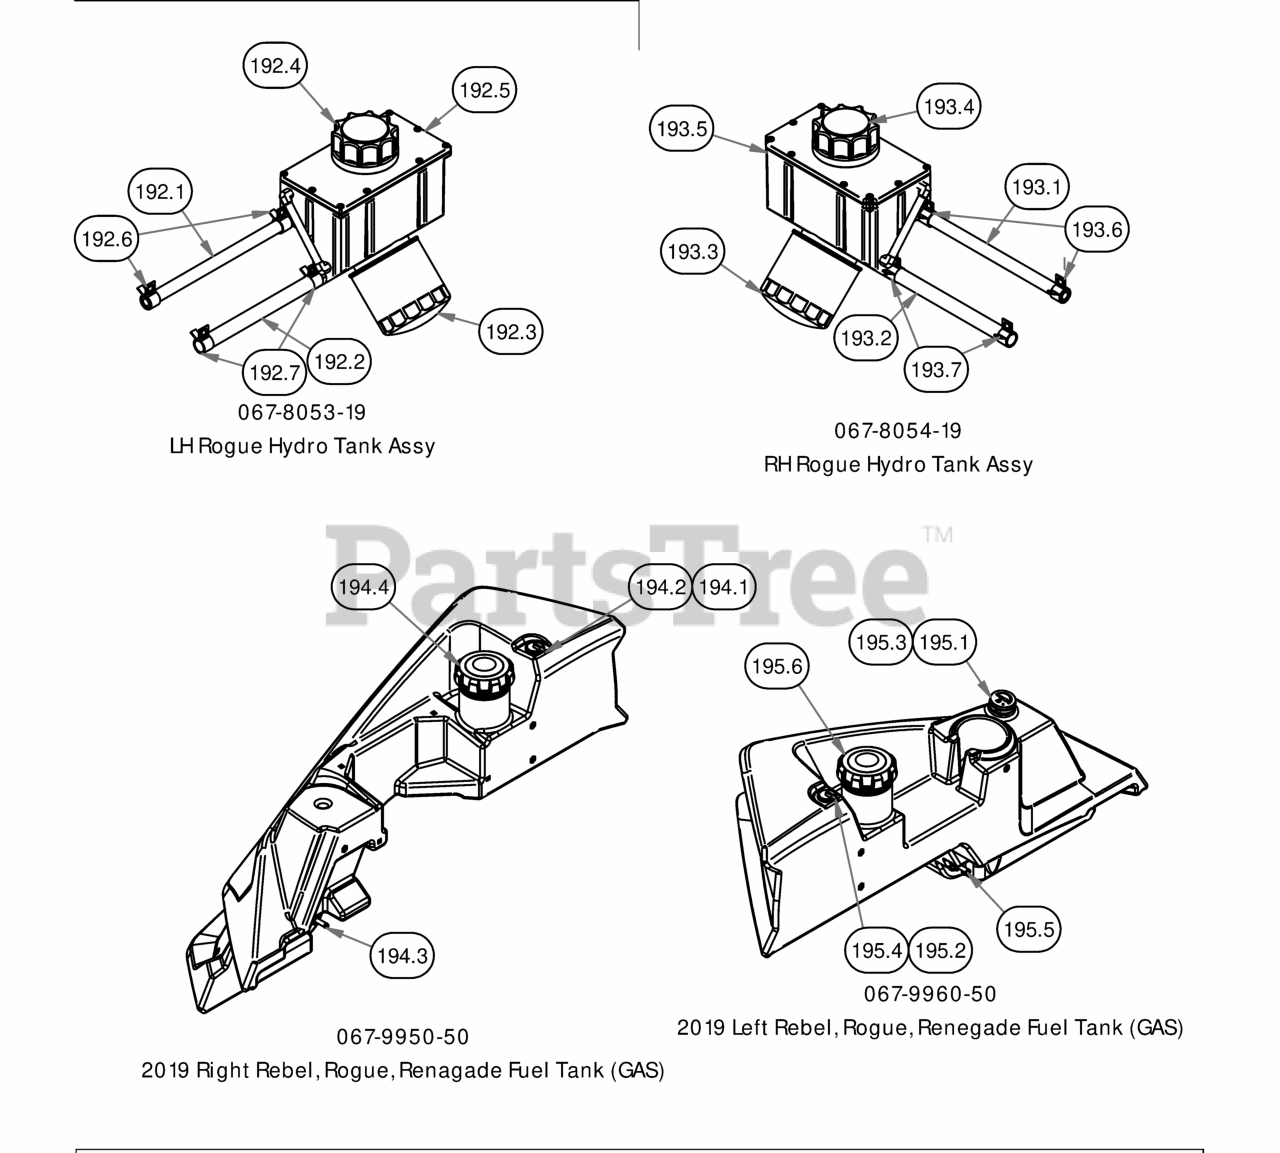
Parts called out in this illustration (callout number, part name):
192.1	3/8" Clear Hose x 4 1/2"
192.2	1/2 Clear Braded Hose Priced/Foot x 9.5"
192.3	Hydraulic Filter
192.4	Hydraulic Tank Cap W/Dipstick
192.5	2019 Left Outlaw Gen2 Hydro Tank Suspension Only
192.6	3/8" Hose Clamp
192.7	1/2 Hose Clamp
193.1	3/8" Clear Hose x 4 1/2"
193.2	1/2 Clear Braded Hose Priced/Foot x 9.5"
193.3	Hydraulic Filter
193.4	Hydraulic Tank Cap W/Dipstick
193.5	2019 Right Outlaw Gen2 Hydro Tank Suspension Only
193.6	3/8" Hose Clamp
193.7	1/2 Hose Clamp
194.1	Roll Over Valve Grommet
194.2	Rollover Valve
194.3	Fuel Pick-up
195.1	Fuel Gauge with Grommet
195.2	Roll Over Valve Grommet
195.3	Fuel Gauge Grommet
195.4	Rollover Valve
195.5	Fuel Pick-up
